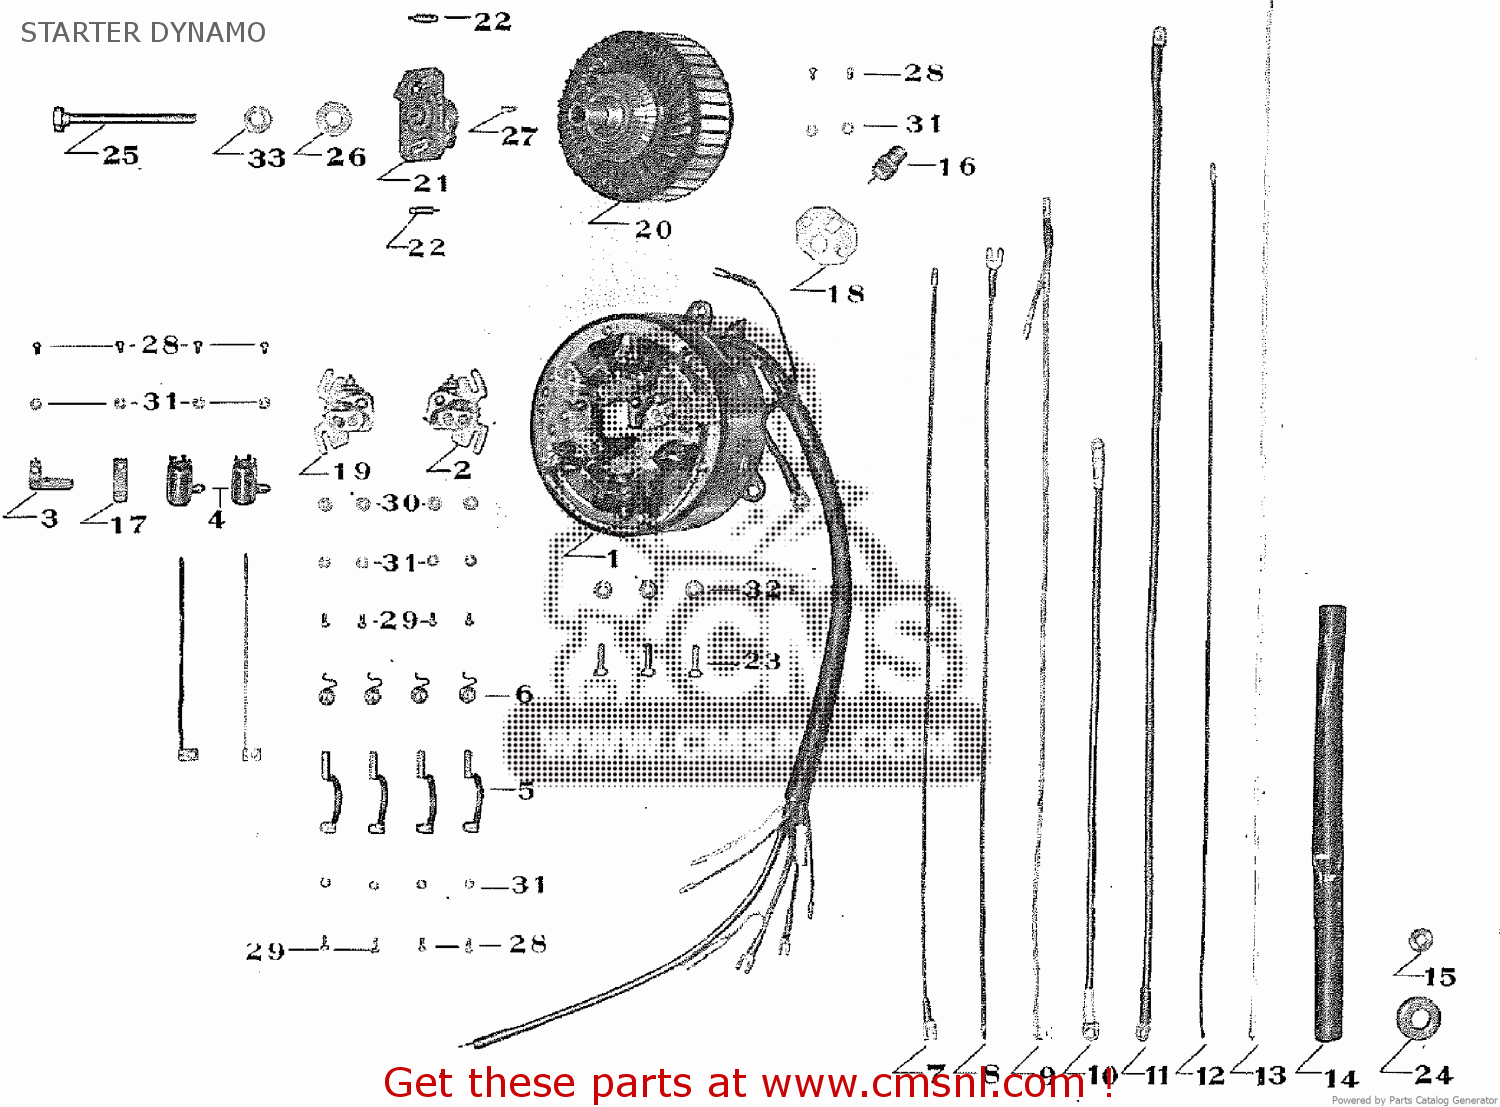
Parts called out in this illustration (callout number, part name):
1	STATOR ASSY
2	RIGHT CONTACT POINT ASSY
3	OIL FELT COMP.
4	CONDENSOR COMP
5	BRUSH COMP.
6	BRUSH SPRING
7	NEUTRAL LEAD CORD
8	FIELD COIL LEAD CORD
9	DYNAMO LEAD CORD
10	MOTOR LEAD CORD
11	BATTERY LEAD CORD
12	IGNITION LEAD CORD (A)
13	IGNITION LEAD CORD (B)
14	WIRE HARNESS TUBE
15	WIRE HARNESS BUSH
16	MOTOR LEAD CORD TERMINAL ASSY
17	TIMING MARK PLATE
18	TERMINAL PLATE
19	LEFT CONTACT POINT ASSY.
20	ARMATURE COMP.
21	GOVERNOR ASSY.
22	GOVERNOR SPRING
23	STATOR SET SCREW
24	WIRE HARNESS BUSH
25	ROTOR SET BOLT
26	ROTOR SET WASHER
27	3MM WOODRUFF KEY
28	4X6 SCREW
29	4X8 SCREW
30	4MM PLANE WASHER
31	4MM PLANE WASHER
32	6MM SPRING WASHER
33	10MM SPRING WASHER
